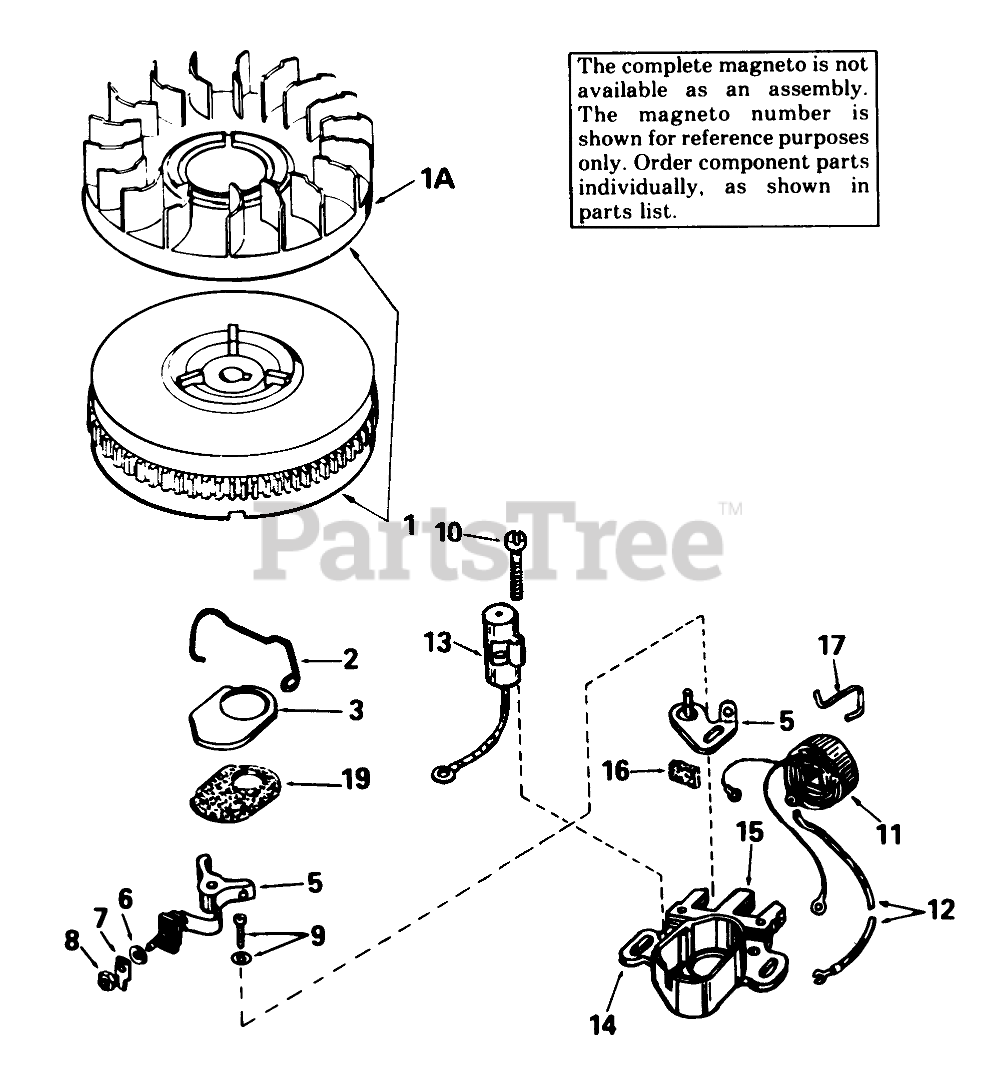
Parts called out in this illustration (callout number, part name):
1	Flywheel (Incl. Ref. #1A)
2	Spring Breaker Box
3	Cover-Dust
5	Breaker Assy.
7	Terminal, Ground
9	Breaker Screw
10	Condenser Screw
11	Coil Assy. (Incl. Ref. #12)
12	Wire, Lead
13	Condenser
14	Core & Plate
15	Stator Assy. (Incl. Ref. #2 thru 11, 13, 14, 16, 17 & 19)
16	Felt,Cam Wiper
17	Clip, Coil
19	Gasket, Dust Cover
